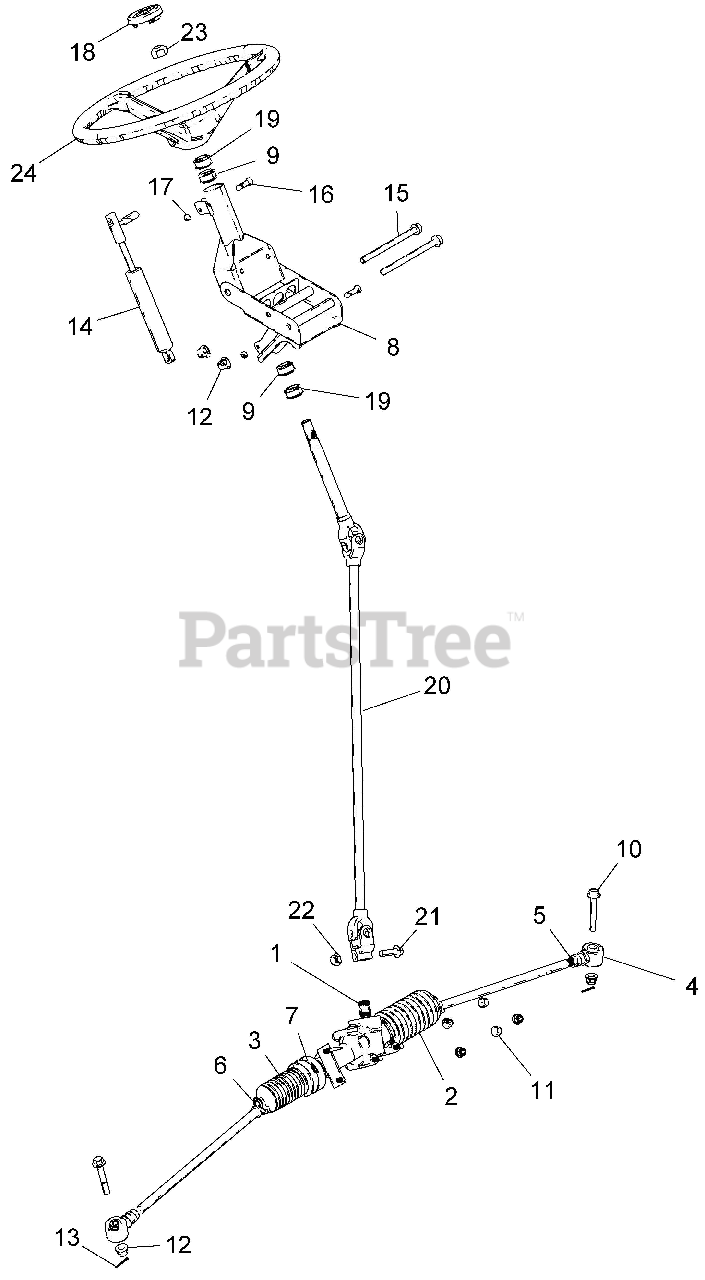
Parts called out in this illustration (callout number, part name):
1	ASM-GEAR BOX,STEERING
2	BOOT-DRIVER SIDE,RACK
3	BOOT-PASSENGER,SIDE RACK
4	END, ROD LH
5	NUT,JAM,LH(10)
6	CLAMP-BOOT,SMALL
7	CLAMP-BOOT,LARGE
8	ASM-TILT,STEERING,RVTD,M10,BLK
9	BEARING-STEERING
10	BOLT-M10X1.25X65,HX WASH HD
11	NUT-M8X1.25,FLG,NYLOC-OLIVE D
12	NUT-M10X1.25,FLG,NYLOC-OLIVE D
13	PIN,COTTER(10)
14	ASM-SHOCK,OIL LOCKING,MACH
15	BOLT-M10X1.25X130,HXFLG-OLIVED
16	BOLT-SHOULDER,M8-15,M6X1.0-BLK
17	NUT,NYLOK(10)
18	CAP, STEERING WHEEL
19	BUSHING-STEERING
20	SHAFT-STEERING,UPPER/LOWER
21	SCR-M10X1.50X35 HX/FL
22	NUT-NY INS,M10X1.5,HEX,ZINC,YW
23	NUT-HEX-M16X2, 8 ZC NYL
24	WHEEL-STEERING,15"
